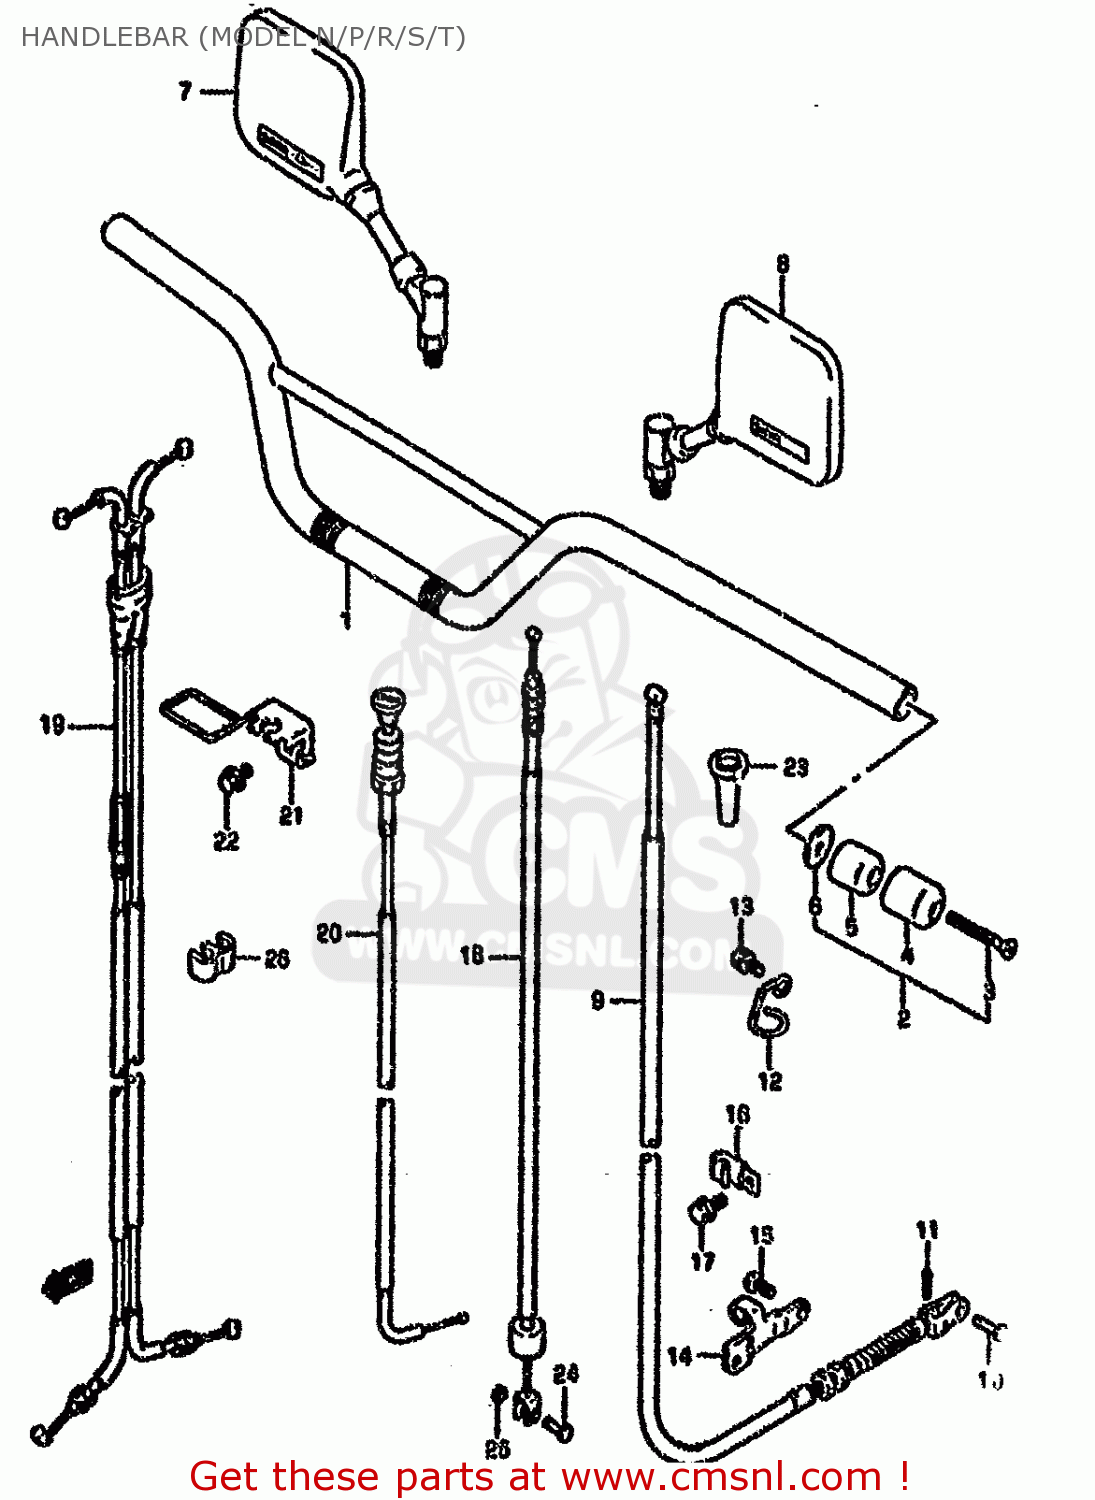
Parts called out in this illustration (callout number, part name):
1	HANDLEBAR
2	BALANCER SET,HANDLEBAR
3	SCREW
4	CAP,BALANCER
5	BALANCER,HANDLEBAR
6	SPACER,BALANCER
7	MIRROR ASSY,RR VIEW,R
8	MIRROR ASSY,RE
9	CABLE ASSY,CLUTCH
10	PIN(L:13)
11	PIN
12	GUIDE
13	BOLT
14	STOPPER,CLUTCH CABLE
15	SCREW
16	CLAMP
17	BOLT
18	CABLE ASSY,DECOMP
19	CABLE ASSY,THROTTLE
20	CABLE,STARTER
21	BRACKET,STARTER CABLE
22	BOLT
23	BOOT,CLUTCH CABLE
24	PIN(4X12.5)
25	E RING
26	CLIP
